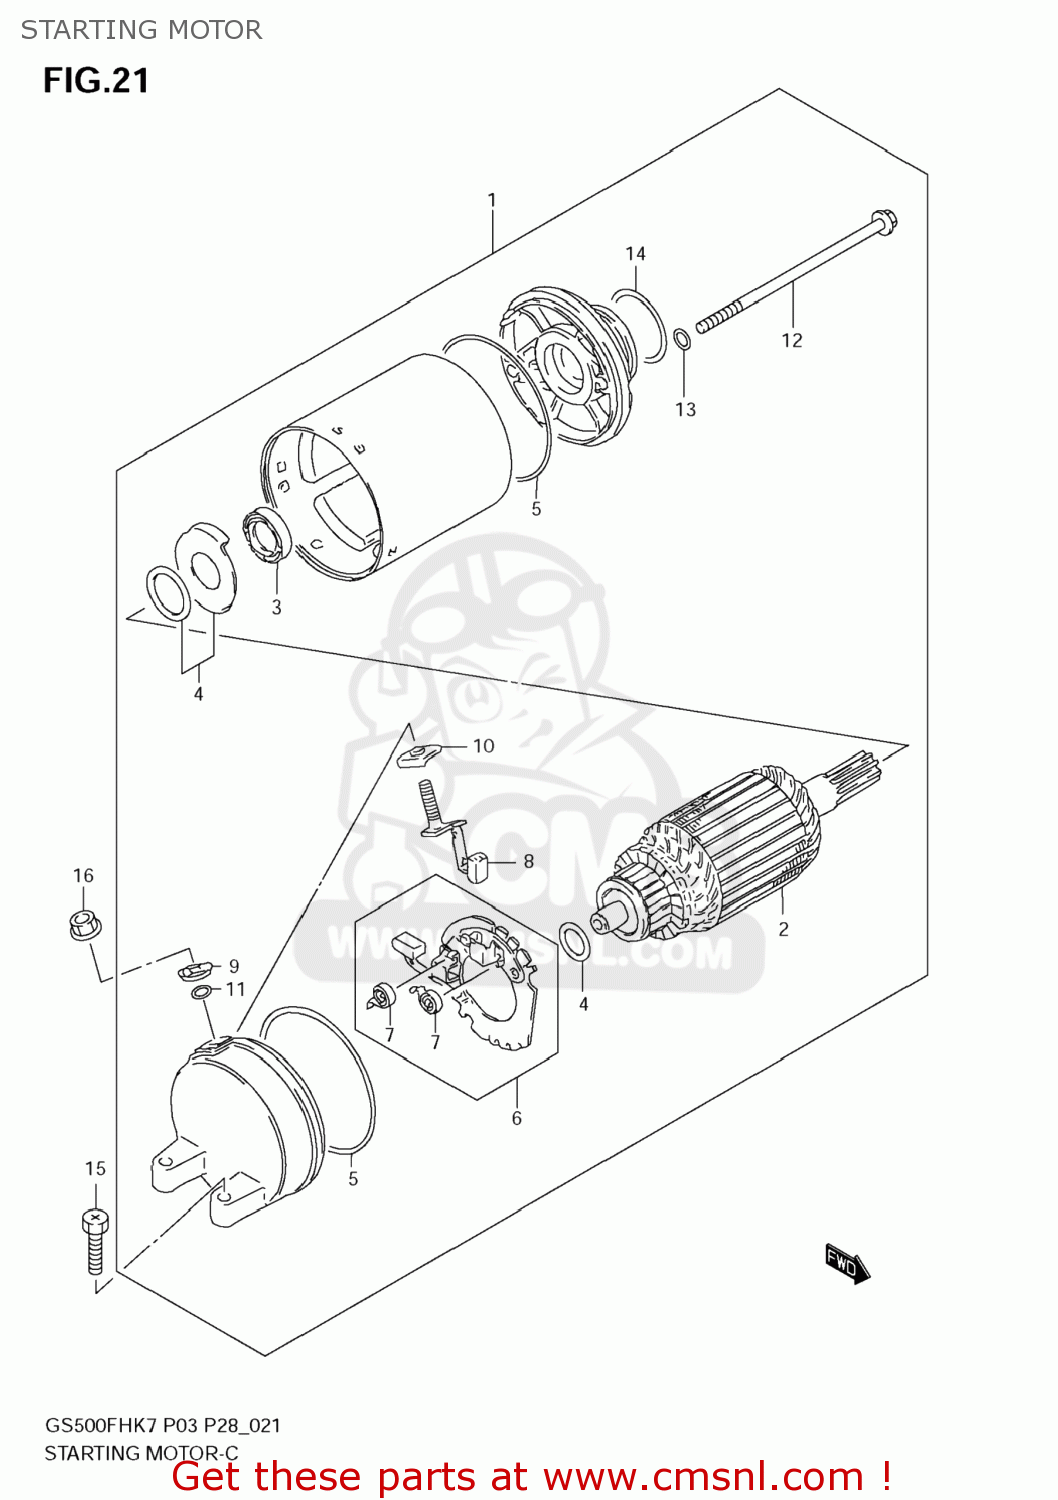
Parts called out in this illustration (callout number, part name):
1	MOTOR ASSY,STARTING
2	ARMATURE
3	SEAL,OIL
4	SHIM SET,STARTING MOTOR
5	O RING
6	HOLDER,BRUSH
7	SPRING
8	BRUSH SUB ASSY,STARTING MOTOR
9	BUSHING
10	BUSH,B
11	O RING
12	BOLT
13	O RING
14	O RING(D:3,ID:24.5)
15	BOLT(6X25)
16	NUT
